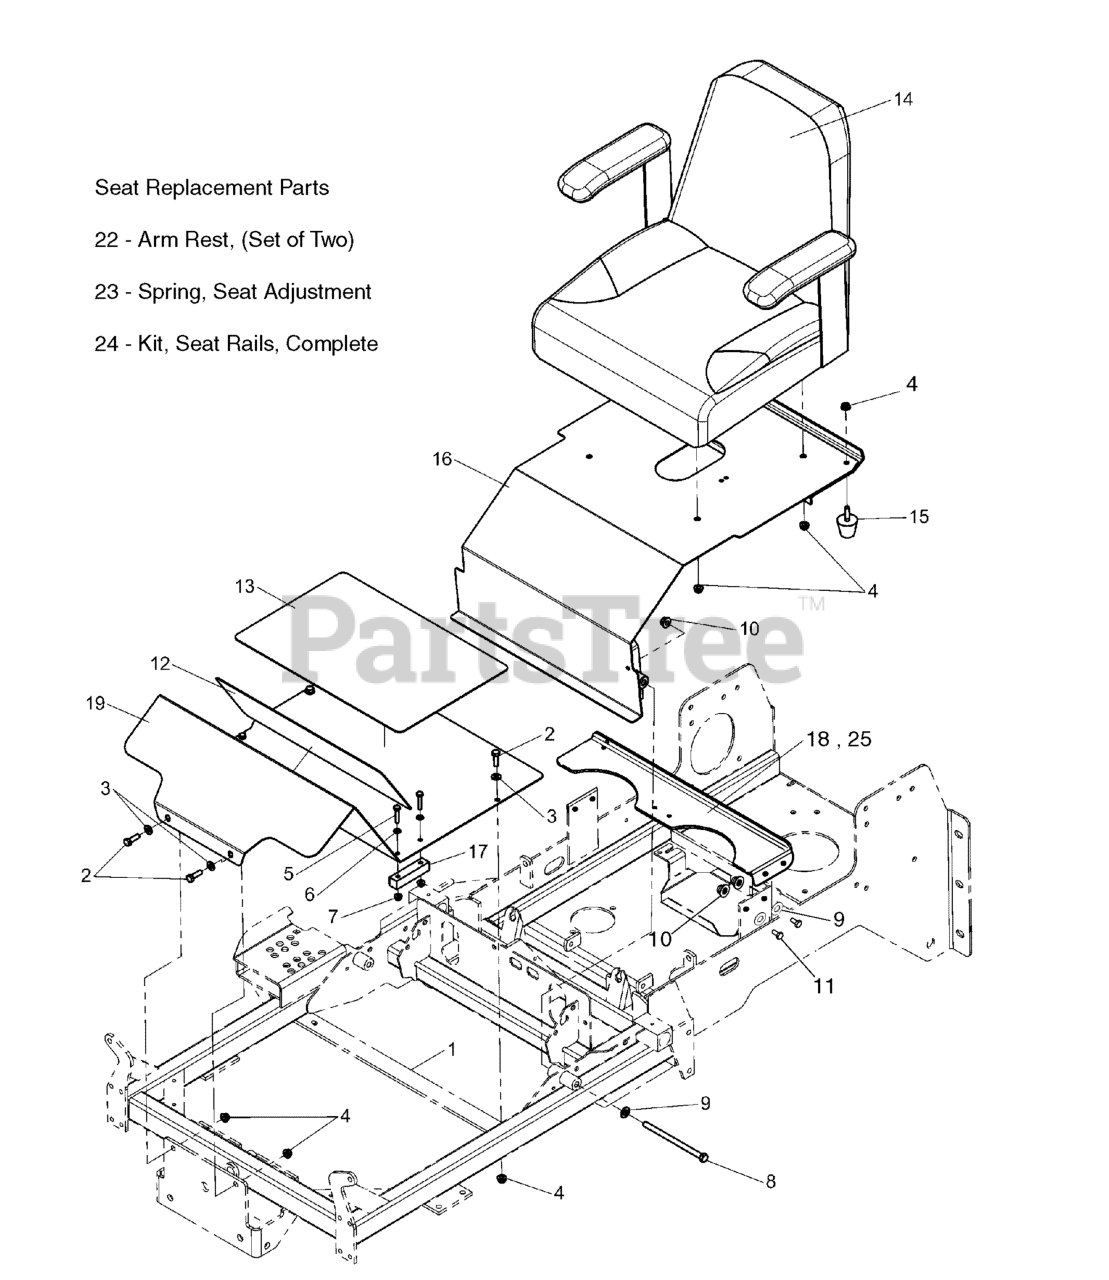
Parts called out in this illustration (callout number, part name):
1	MAIN FRAME
2	BOLT, 5/16-18 X 1 GD5 YZ
3	WASHER 5/16" Gr. 9 Flat
4	NUT, 5/16-18 Hex Nylock Flange
5	BOLT, 1/4-20 X 1-1/4
6	WASHER, 1/4 SAE
7	NUT, 1/4-20 Hex Nylock Flange
8	BOLT, 3/8-16 X 6" GD5 CZ
9	WASHER, 3/8 SAE
10	NUT, 3/8-16 Hex Nylock Flange
11	BOLT, 3/8-16 X 1" GD5 CZ
12	SAFETY WALK, FLOOR REST
13	SAFETY WALK, FLOOR PLATE
14	SEAT, BLACK
15	RUBBER BUMPER
16	SEAT PLATE
16	SEAT PLATE W/ DECALS, IS1500Z W/ROPS
17	BLOCK, DECK LIFT SUPPORT
18	SUPPORT, SEAT PLATE
19	PLATE, FLOOR
22	ARM REST (SET OF 2)
23	SPRING, EXTENSION, SEAT ADJUSTMENT (BLK OR SLVR)
24	KIT, SEAT RAILS, COMPLETE
25	PLATE, SEAT SUPPORT - RED
